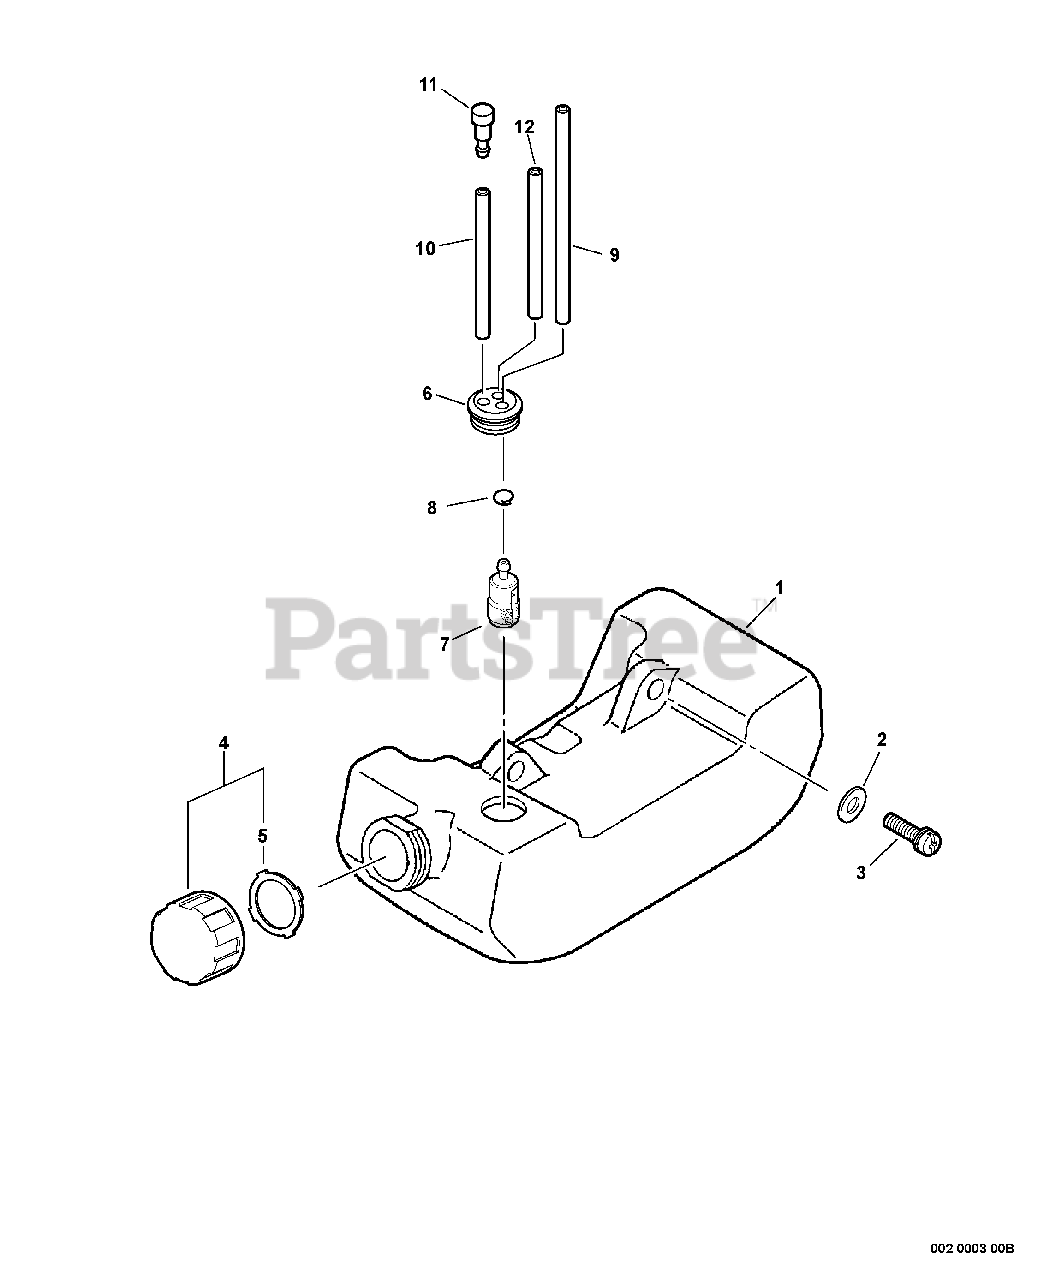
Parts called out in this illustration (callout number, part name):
1	TANK, FUEL
2	WASHER 5.5×12×0.8
3	SCREW 5×16
4	CAP ASSY, FUEL
5	GASKET, FUEL CAP
6	GROMMET, FUEL
7	FILTER, FUEL
8	CLIP 6 MM
9	PIPE, FUEL 3x-5x-180
10	PIPE, FUEL 3x-5x-70 BLACK
11	VENT ASSY
12	PIPE, FUEL RETURN 3×6×90 MM CLEAR
